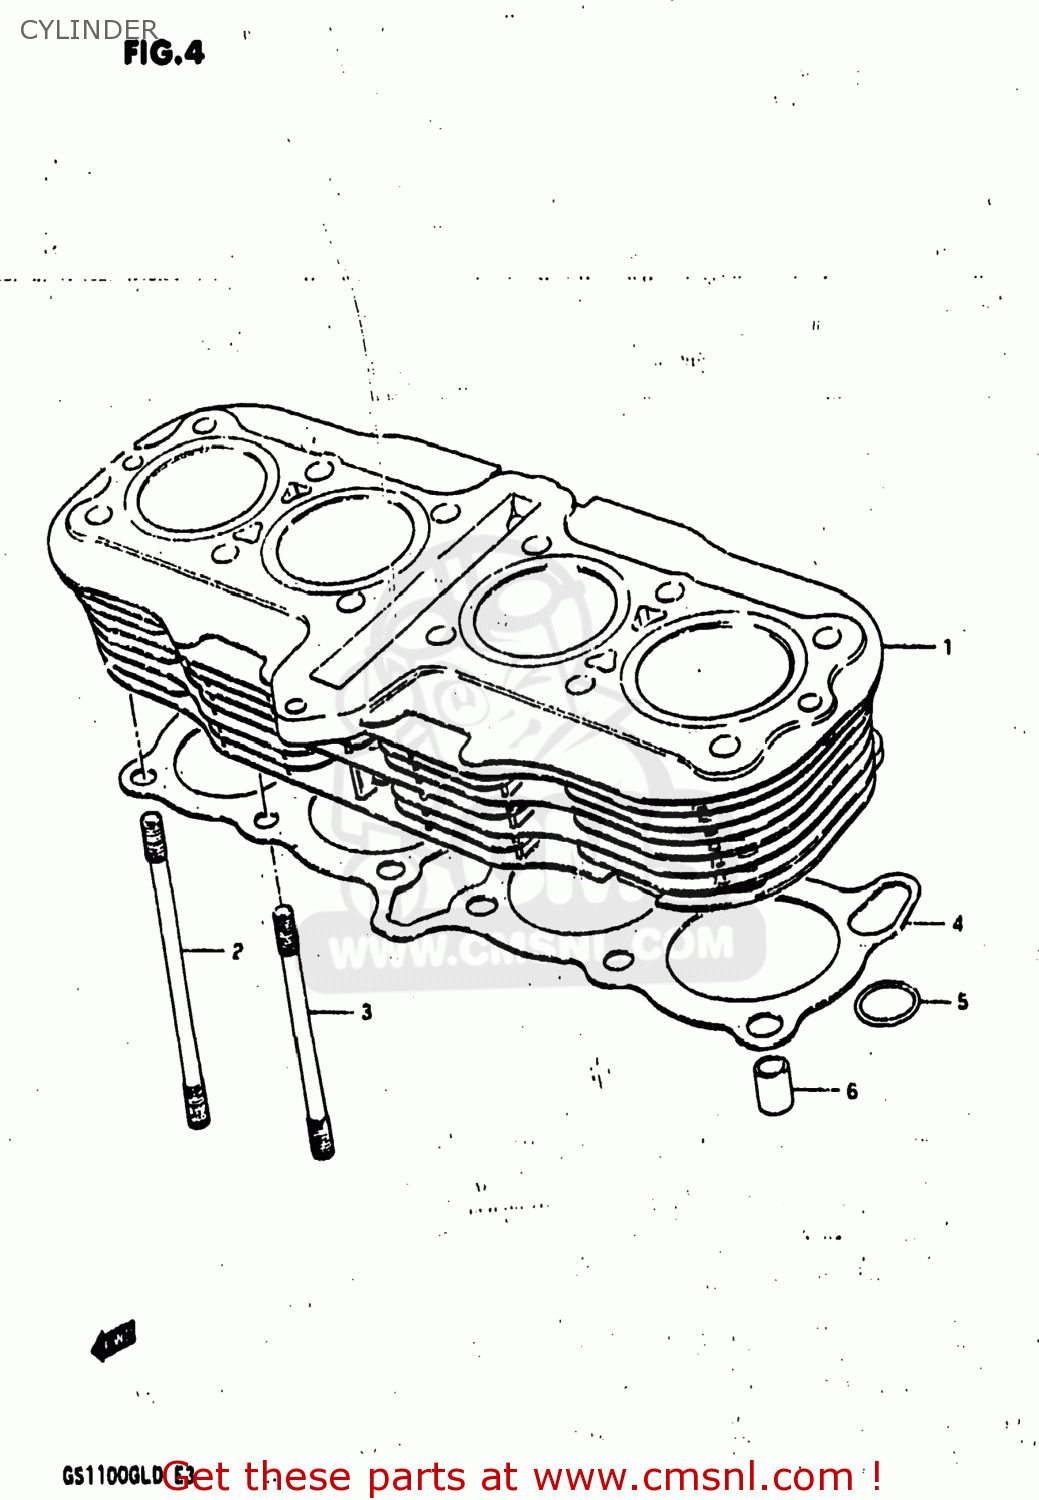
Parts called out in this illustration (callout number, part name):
1	CYLINDER
2	BOLT,STUD
3	STUD
4	GASKET,CYLINDER (MCA)
5	O RING(D:3.5)
6	PIN
